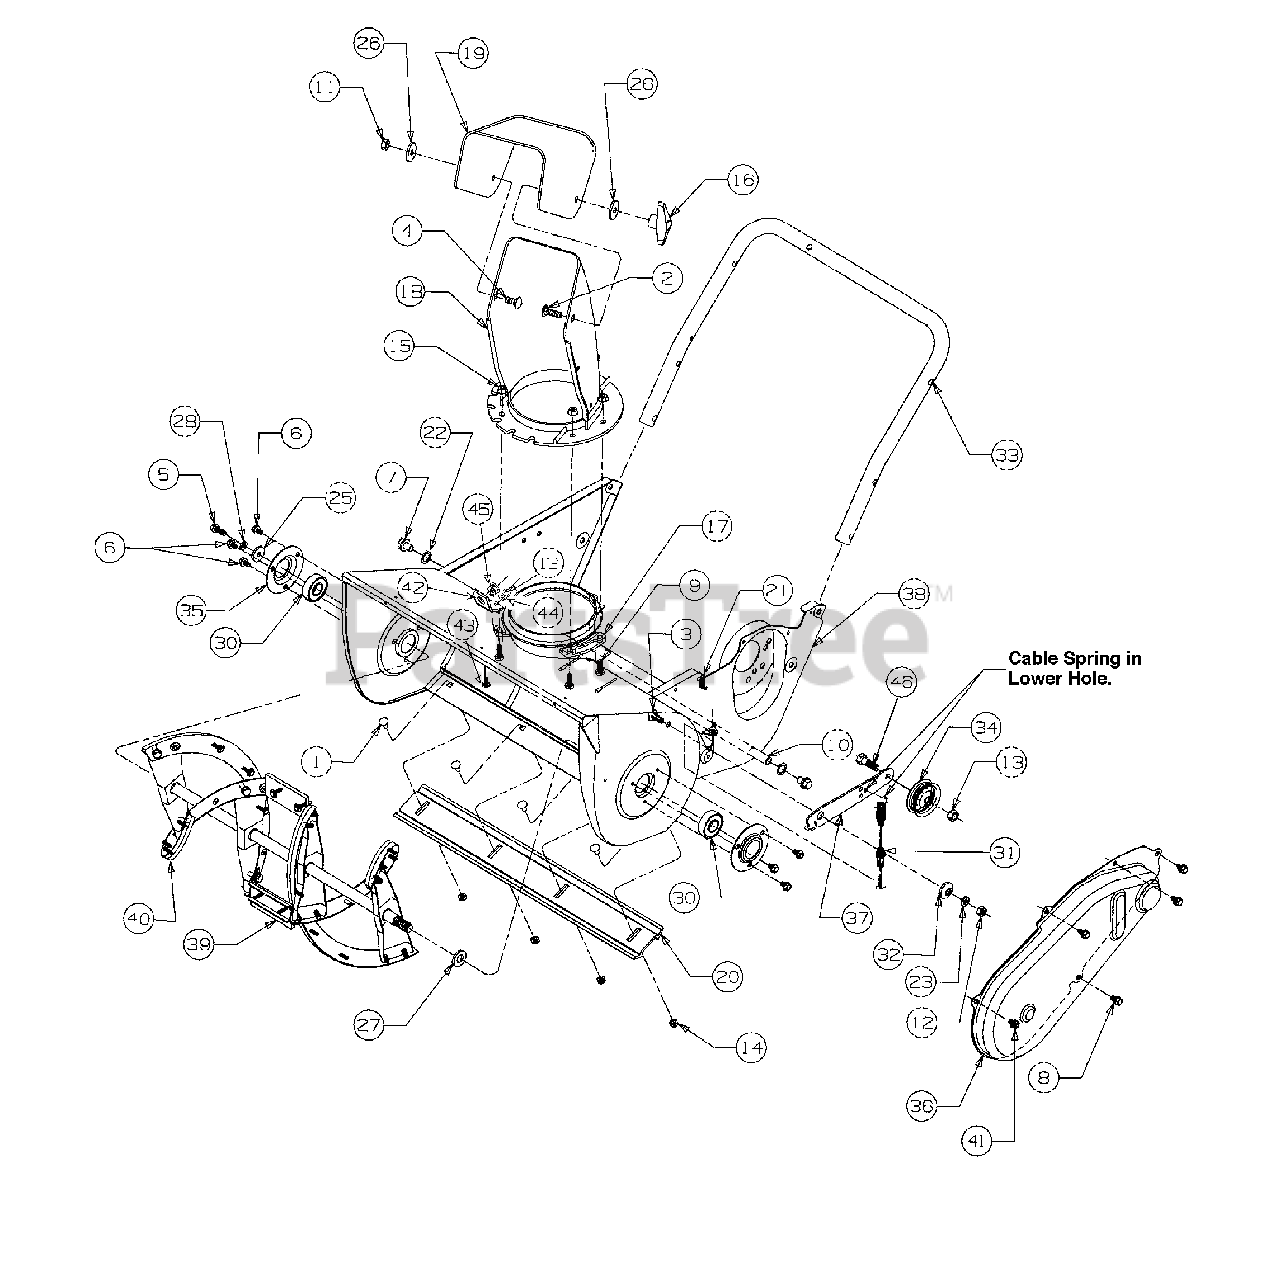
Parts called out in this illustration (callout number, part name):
1	Carriage Bolt
2	Carriage Bolt
3	Pan Head Screw
4	Carriage Bolt
5	Hex Washer Screw
6	Hex Washer Screw
7	Hex Washer Screw
8	Hex Washer Screw
9	Hex Cap Screw
10	Axle
11	Hex Center Lock Nut
12	Hex Nut
13	Hex Lock Nut
14	Hex Lock Flange Nut
15	Hex Lock Flanged Nut
17	Chute Keeper
18	Lower Chute
19	Upper Chute
20	Shave Plate
21	Extension Spring
22	Flat Washer
23	Lock Washer
25	Flat Washer
26	Washer
27	Flat Washer
28	Lock Washer
30	Ball Bearing
31	Cable-Clutch
32	Spacer
40	Auger Rubber Replacement
41	Hex Washer Screw
44	Bell Washer
45	Bushing
46	Hex Screw
